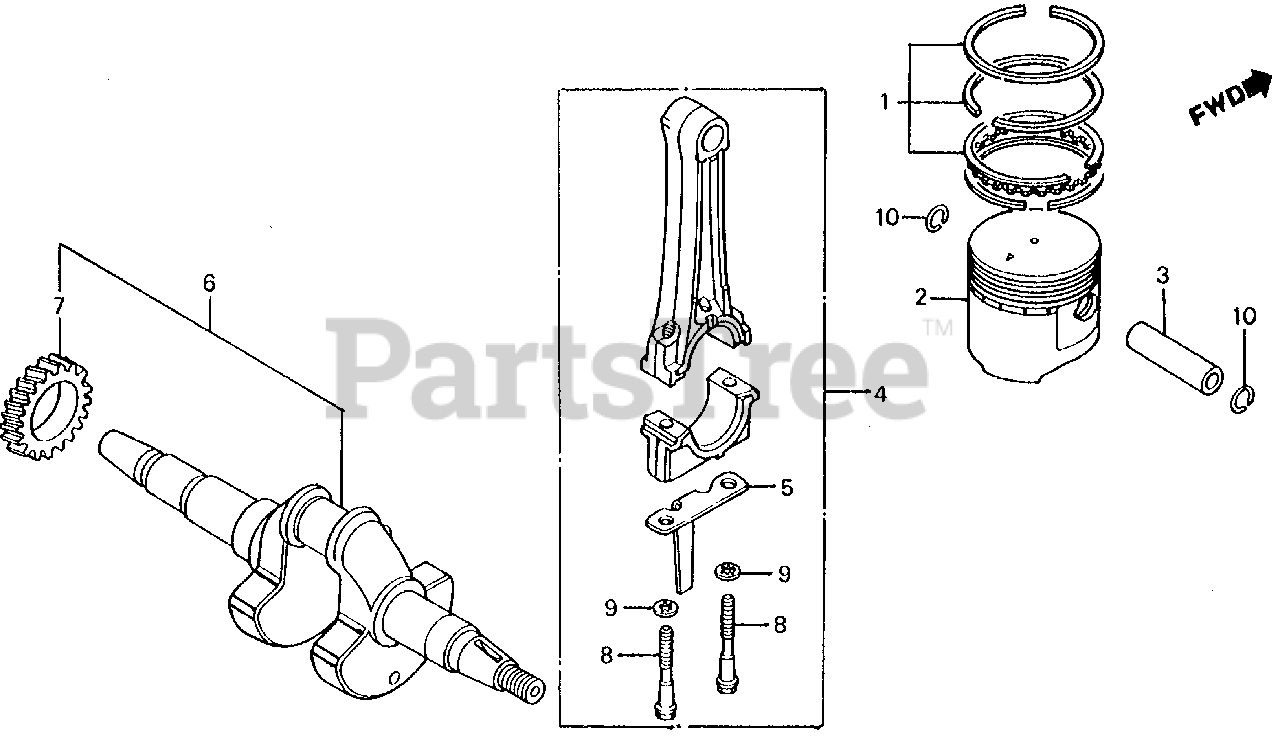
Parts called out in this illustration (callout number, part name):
1	RING SET, PISTON (STD)
1	RING SET, PISTON (OS 0.25)
1	RING SET, PISTON (OS 0.50)
1	RING SET, PISTON (0.75)
2	PISTON (STD)
2	PISTON (OS 0.25)
2	PISTON (OS 0.50)
2	PISTON (0.75)
3	PIN, PISTON
4	ROD ASSY., CONNECTING
5	DIPPER, CONNECTING ROD
6	CRANKSHAFT
7	GEAR, TIMING
8	BOLT, CONNECTING ROD (7MM)
9	WASHER, LOCK (7MM)
10	CLIP, PISTON PIN (15MM)
